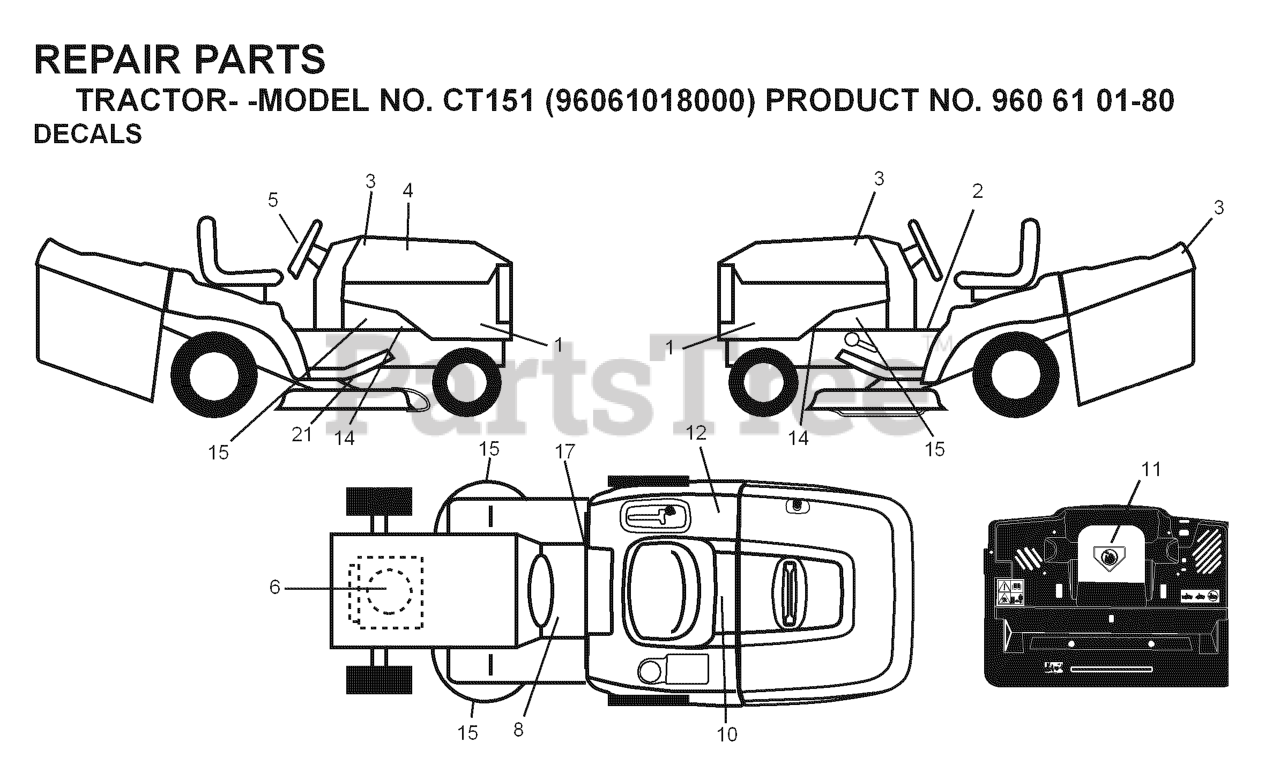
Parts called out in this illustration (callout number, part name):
1	BALL BEARING 6202-2RS1
5	NUT
7	LOCKNUT M8
9	WASHER
10	BEARING FLANGE
12	SCREW ITXPANTT M5X10 ZPB (A00
13	SCREW M6S 8X25
16	SCREW EHHFM
20	SCREW EHHFM
21	WASHER BRB 8.4X17
